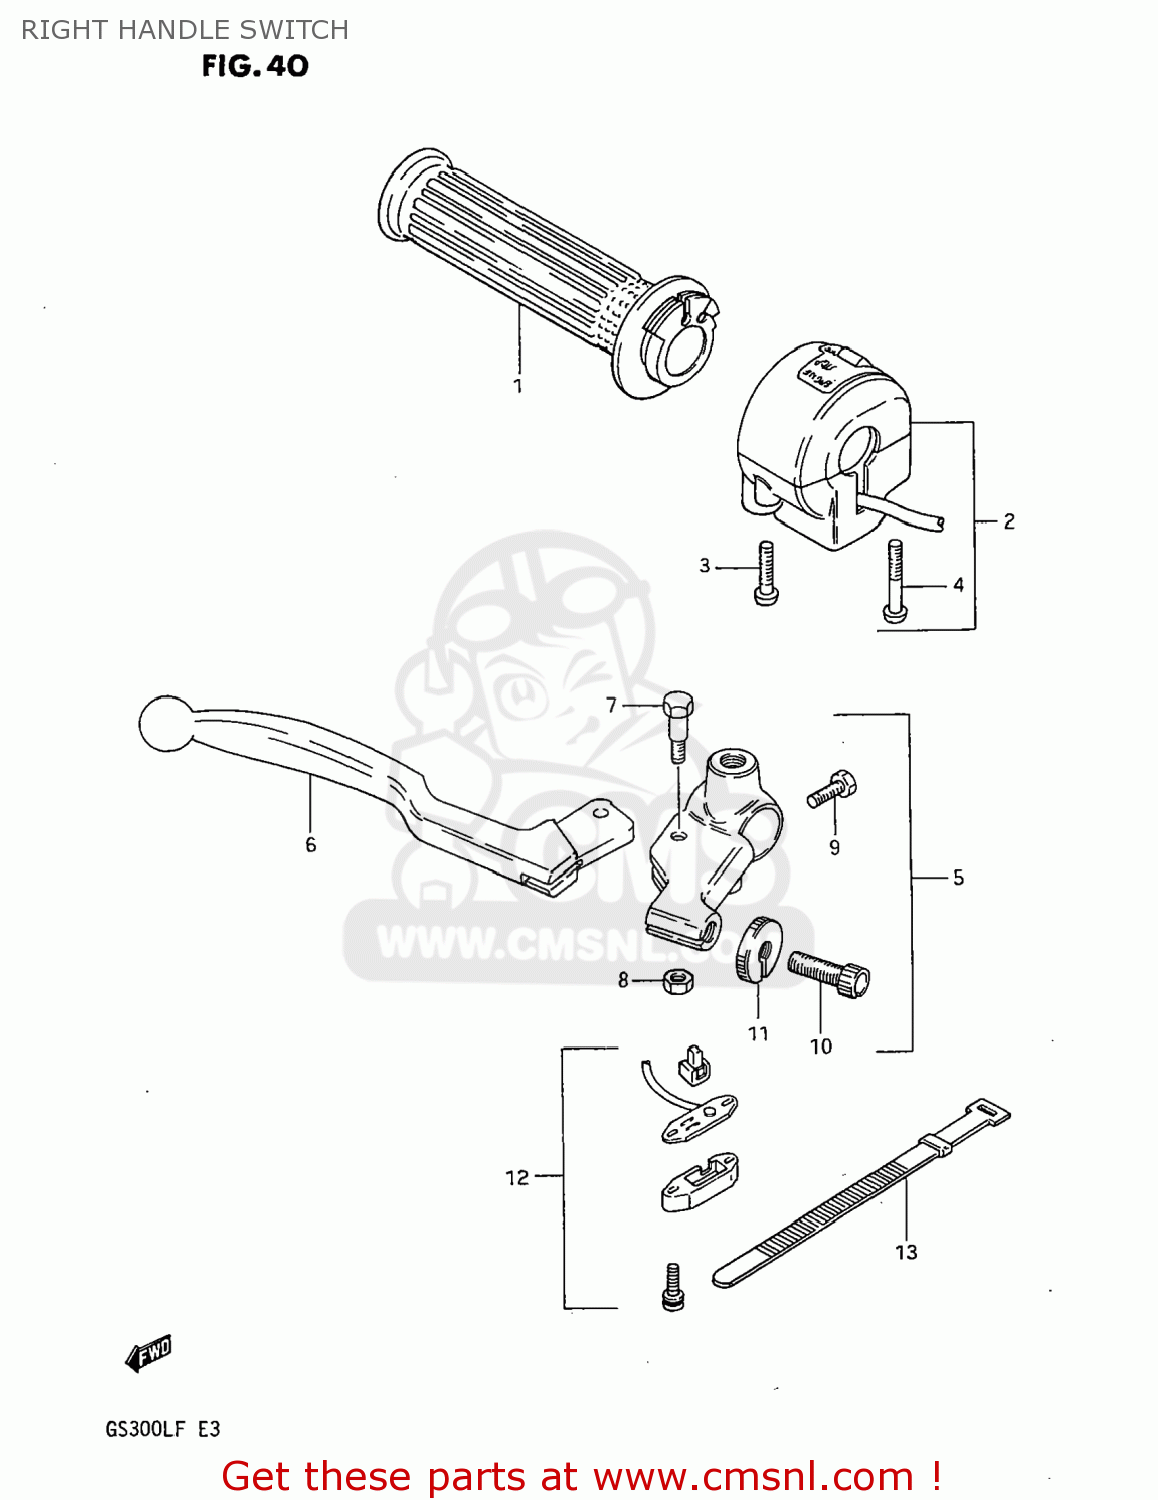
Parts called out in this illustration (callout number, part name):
1	GRIP,THROTTLE
2	SWITCH ASSEMBLY,HANDLE,RIGHT
3	SCREW
4	SCREW
5	LEVER ASSEMBLY,BRAKE
6	LEVER,BRAKE
7	BOLT,LEVER
8	NUT 6MM
9	SCREW
10	ADJUSTER,CABLE
11	NUT,CABLE ADJUSTER
12	SWITCH ASSY,STOP
13	CLAMP(L:120)
